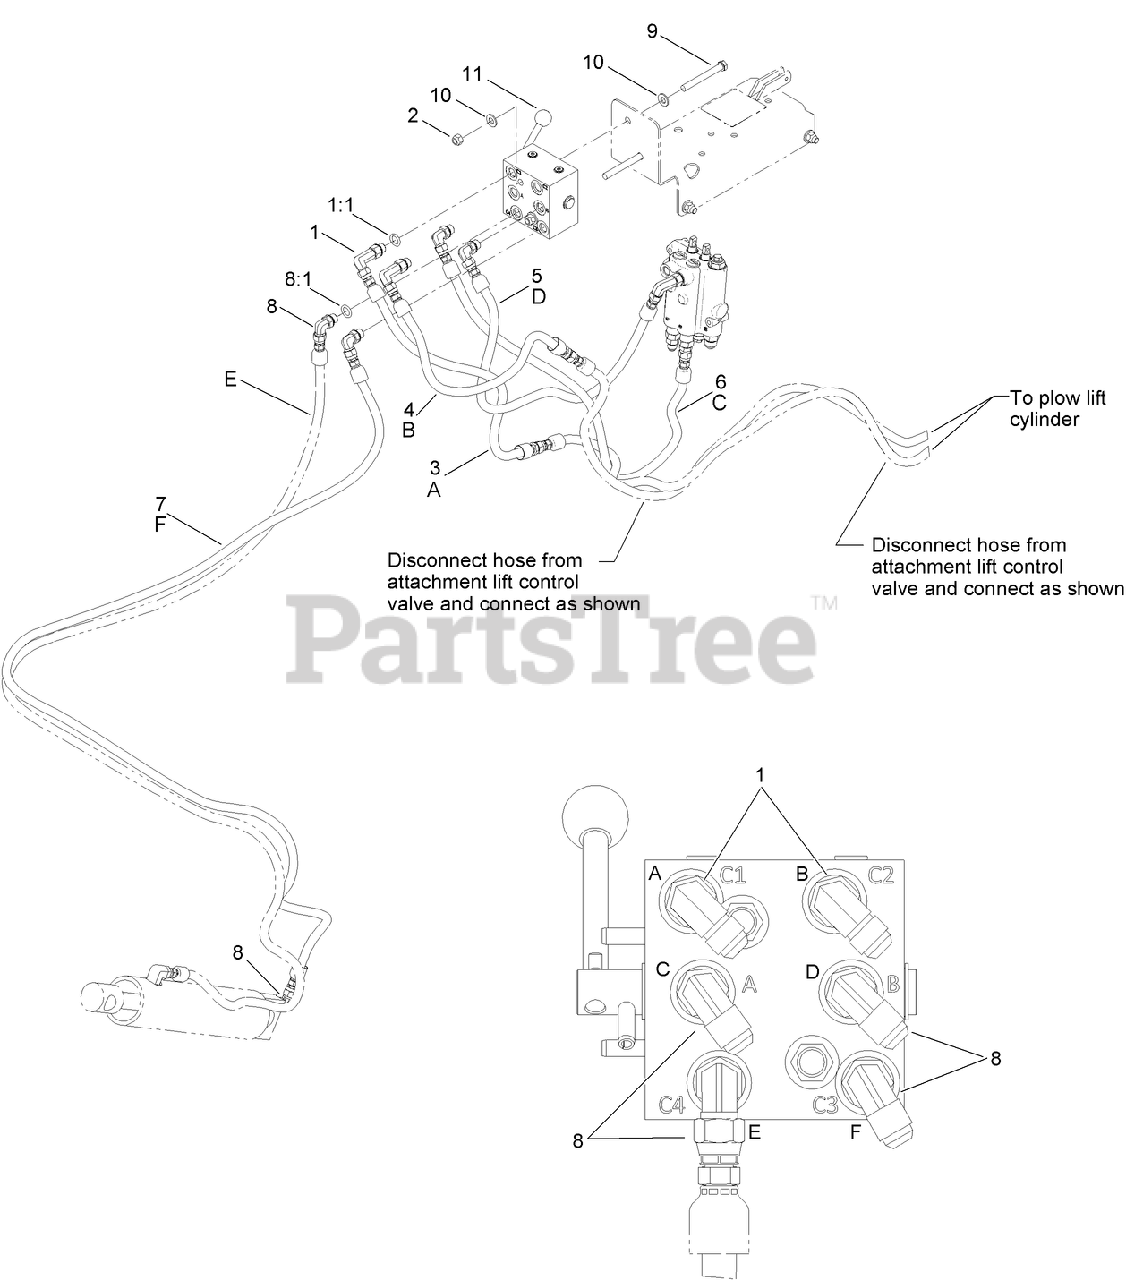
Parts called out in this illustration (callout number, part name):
1	FITTING-ADAPTOR, 90 DEG
1:1	O-RING
2	NUT-HEX
3	HOSE ASM
4	HOSE ASM
5	HOSE ASM
6	HOSE ASM
7	HOSE ASM
8	FITTING-ELBOW, 90 DEG
8:1	O-RING
10	WASHER-FLAT
11	CONTROL SELECTOR VALVE ASM
